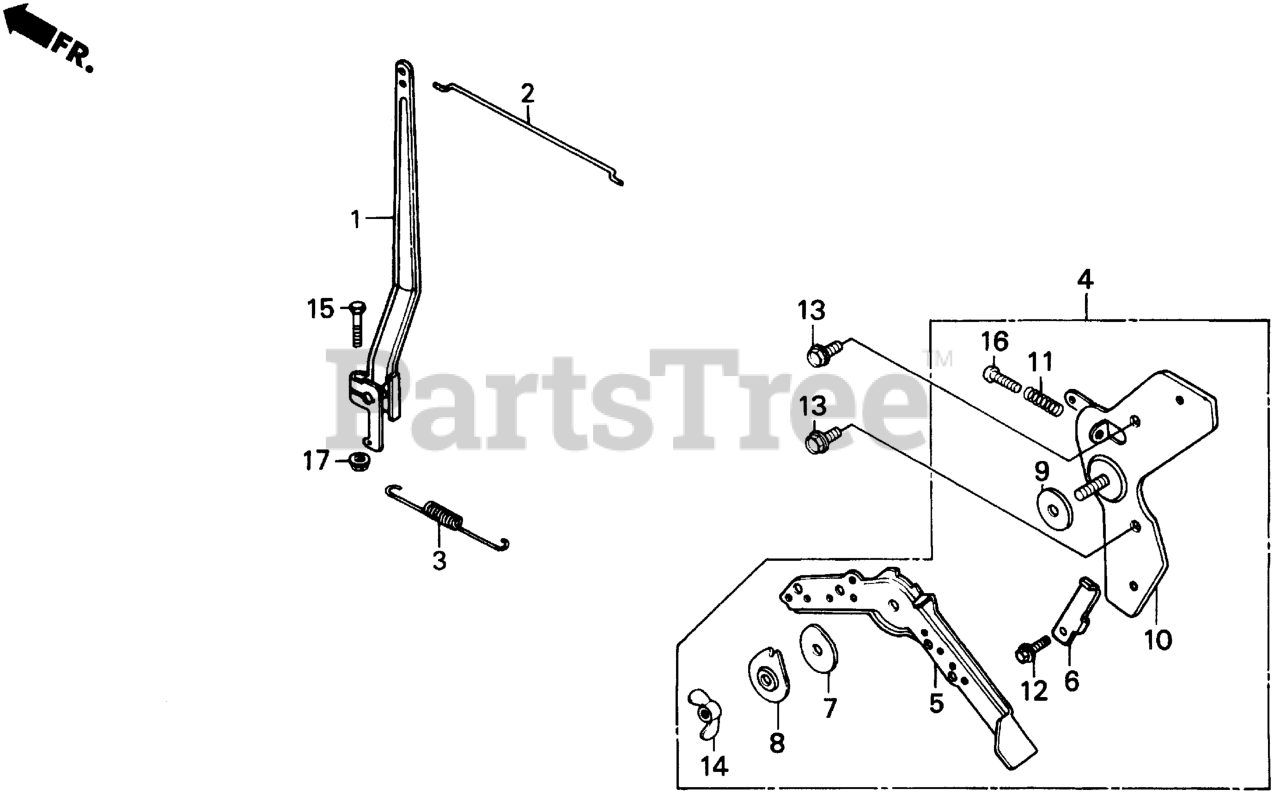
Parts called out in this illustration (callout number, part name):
1	ARM, GOVERNOR
2	ROD, GOVERNOR
3	SPRING, GOVERNOR
4	CONTROL ASSY.
5	LEVER, CONTROL Use from Engine SN 2327377.
7	SPRING, LEVER Use from Engine SN 2327377.
8	WASHER, CONTROL LEVER Use from Engine SN 2327377.
9	SPACER, CONTROL LEVER Use from Engine SN 2327377.
10	BASE, CONTROL LEVER
11	SPRING, CONTROL ADJUSTING Use from Engine SN 2327377.
12	BOLT, FLANGE (5X10) Use from Engine SN 2327377.
13	BOLT, FLANGE (6X12) (CT200)
14	WINGNUT (6MM) Use from Engine SN 2327377.
15	BOLT, HEX. (6X25)
16	SCREW, PAN (5X22)
17	NUT, FLANGE (6MM)
